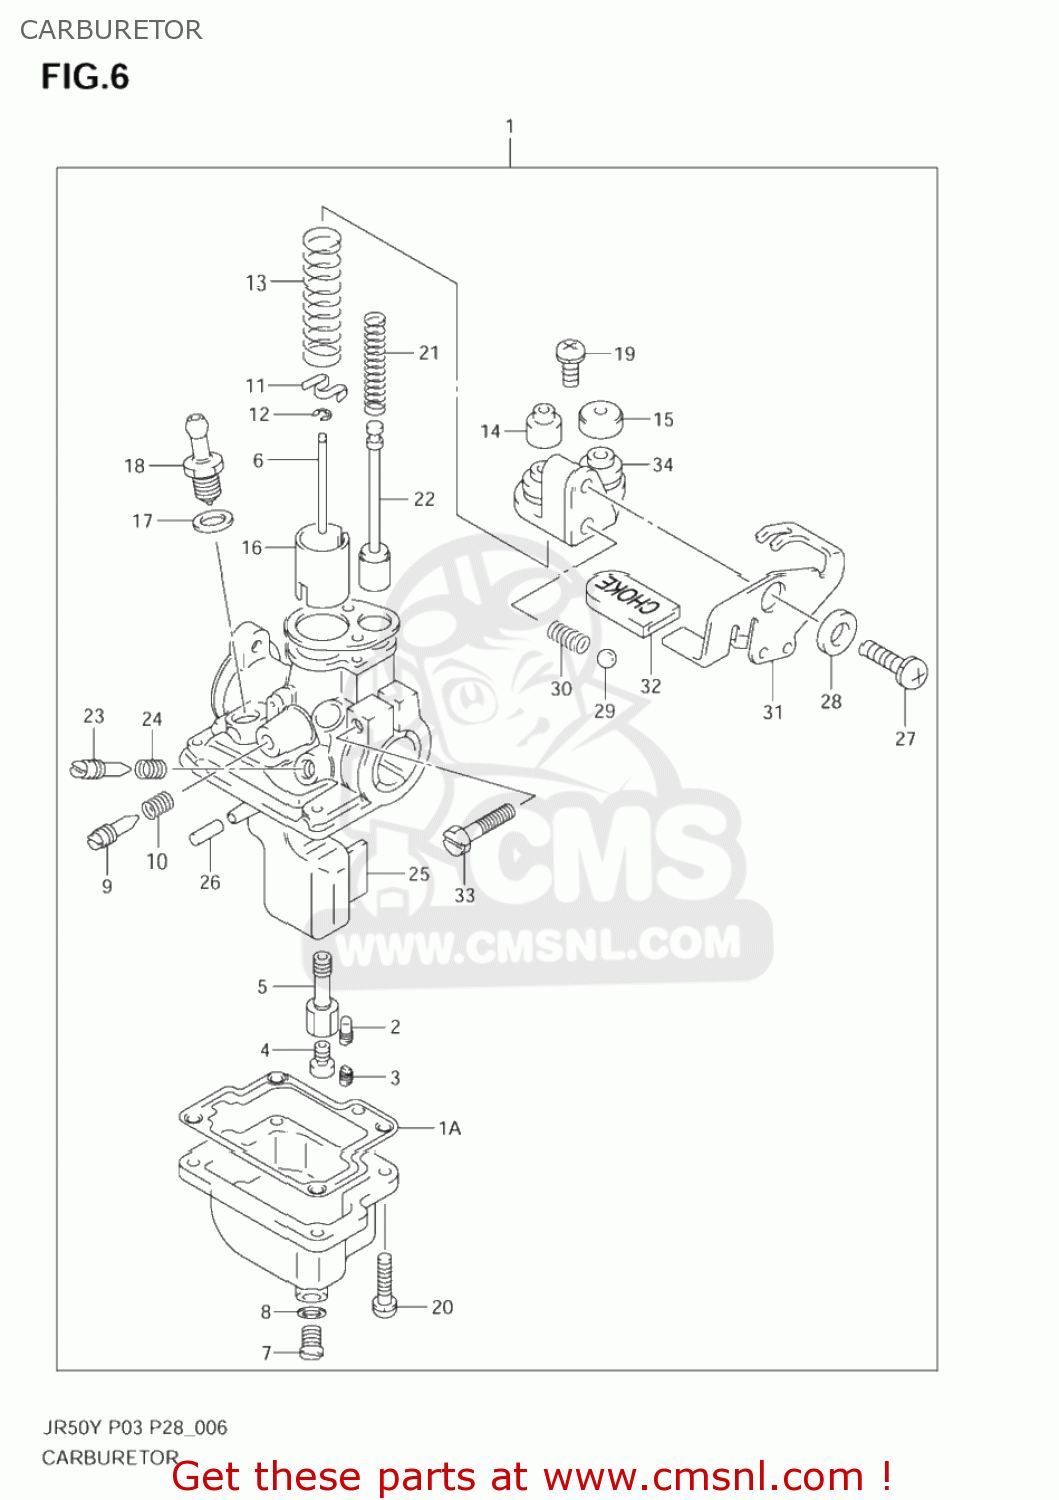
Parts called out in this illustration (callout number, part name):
1	CARBURETOR ASSY
1A	GASKET,FLOAT CAHMBER (NAS)
2	JET,PILOT(15)
3	JET,PILOT
4	JET,MAIN(56.3)
5	JET,NEEDLE(E-6)
6	NEEDLE,JET
7	PLUG
8	GASKET,DRAIN,PLUG (NAS)
9	SCREW,THROTTLE STOP
10	SPRING
11	SEAT,THROTTLE VALVE SPRING
12	CLIP,NEEDLE
13	SPRING,THROTTLE VALVE
14	CAP
15	RUBBER,THROTTLE VALVE CAP
16	VALVE,THROTTLE
17	GASKET,THRO VALVE INSPECTION (NAS)
18	VALVE ASSY,NEEDLE
19	SCREW
20	SCREW
21	SPRING
22	VALVE,STARTER
23	SCREW,AIR
24	SPRING
25	FLOAT
26	PIN,FLOAT
27	SCREW
28	RING,CARBURETOR STARTER
29	BALL,STARTER SHAFT
30	SPRING,STARTER SHAFT
31	LEVER,STARTER
32	CAP,LEVER
33	BOLT
34	TOP ASSY
